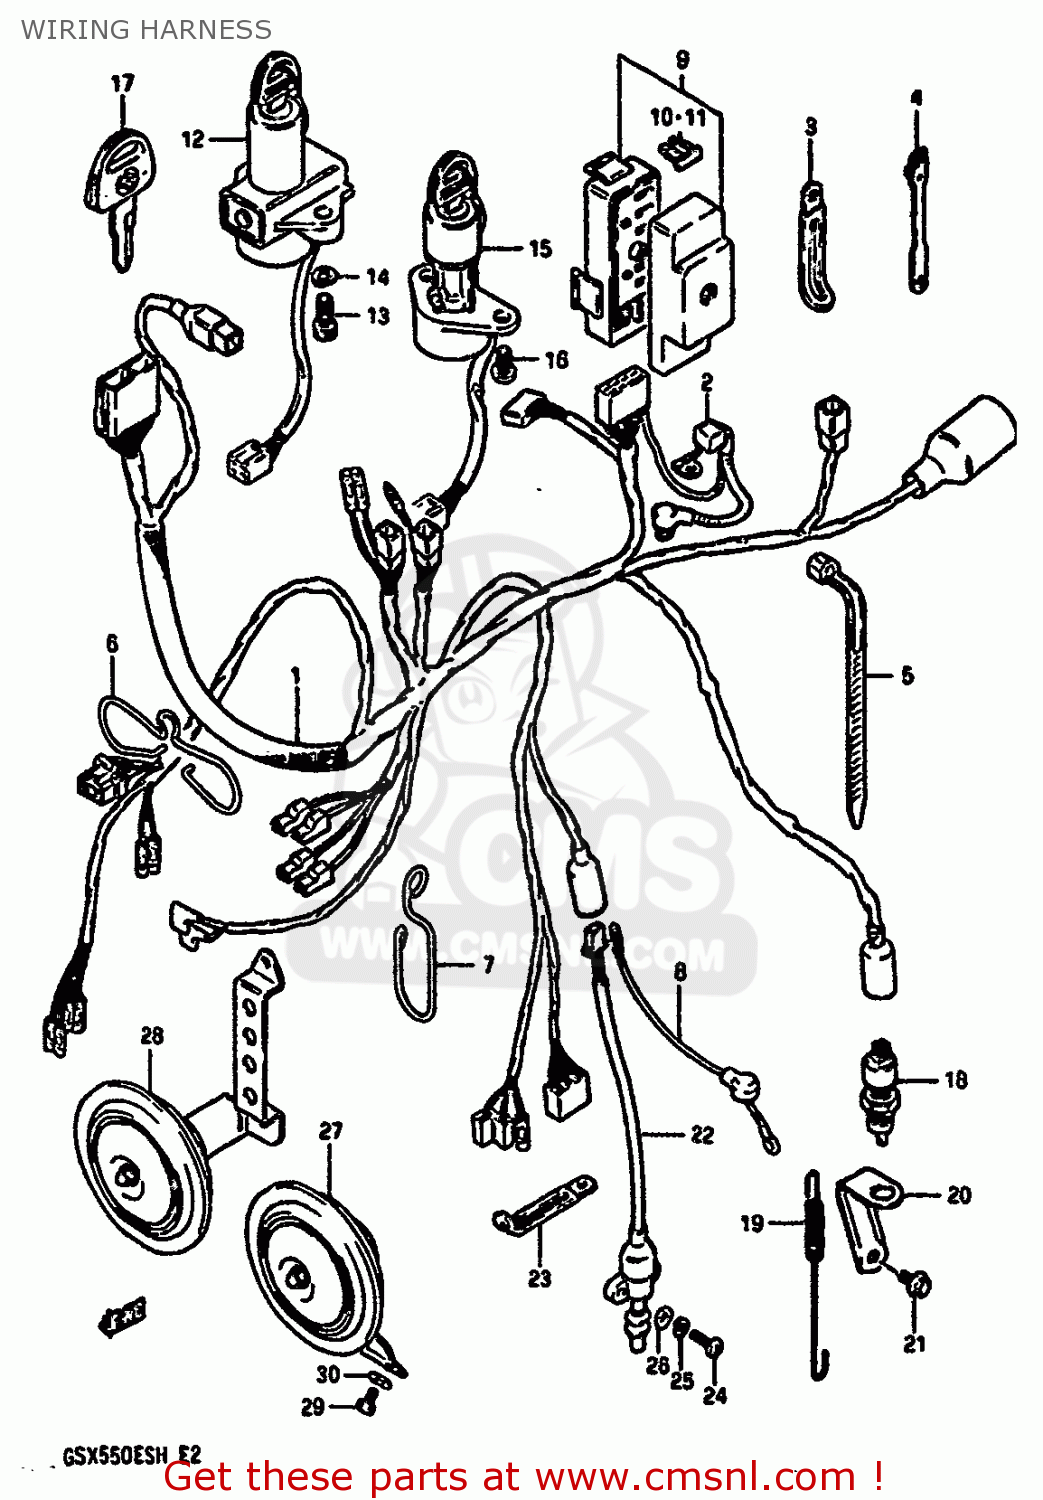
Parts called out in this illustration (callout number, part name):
1	HARNESS,WIRING
2	CAP,BATTERY PLUS TERMINAL
3	CLAMP
4	CLAMP,L:88
5	CLAMP(L:95)
6	BOOT,WIRING HARNESS
7	GUIDE,WIRING HARNESS
8	WIRE
9	FUSE BOX ASSY
10	FUSE(10A)
11	FUSE(15A)
12	IGNITION SWITCH/STEERING LOCK
13	BOLT
14	WASHER,LOCK
15	SWITCH ASSY,IGNITION
16	SCREW 6X12
17	KEY,BLANK
18	SWITCH ASSEMBLY,STOP LAMP
19	SPRING
20	BRACKET,BRAKE LAMP SWITCH
21	BOLT
22	SWITCH ASSEMBLY,SIDE STAND
23	CLAMP
24	SCREW 5X20
25	WASHER,LOCK
26	WASHER,5MM
27	HORN ASSY
28	HORN ASSY
29	BOLT
30	WASHER, LOWER
